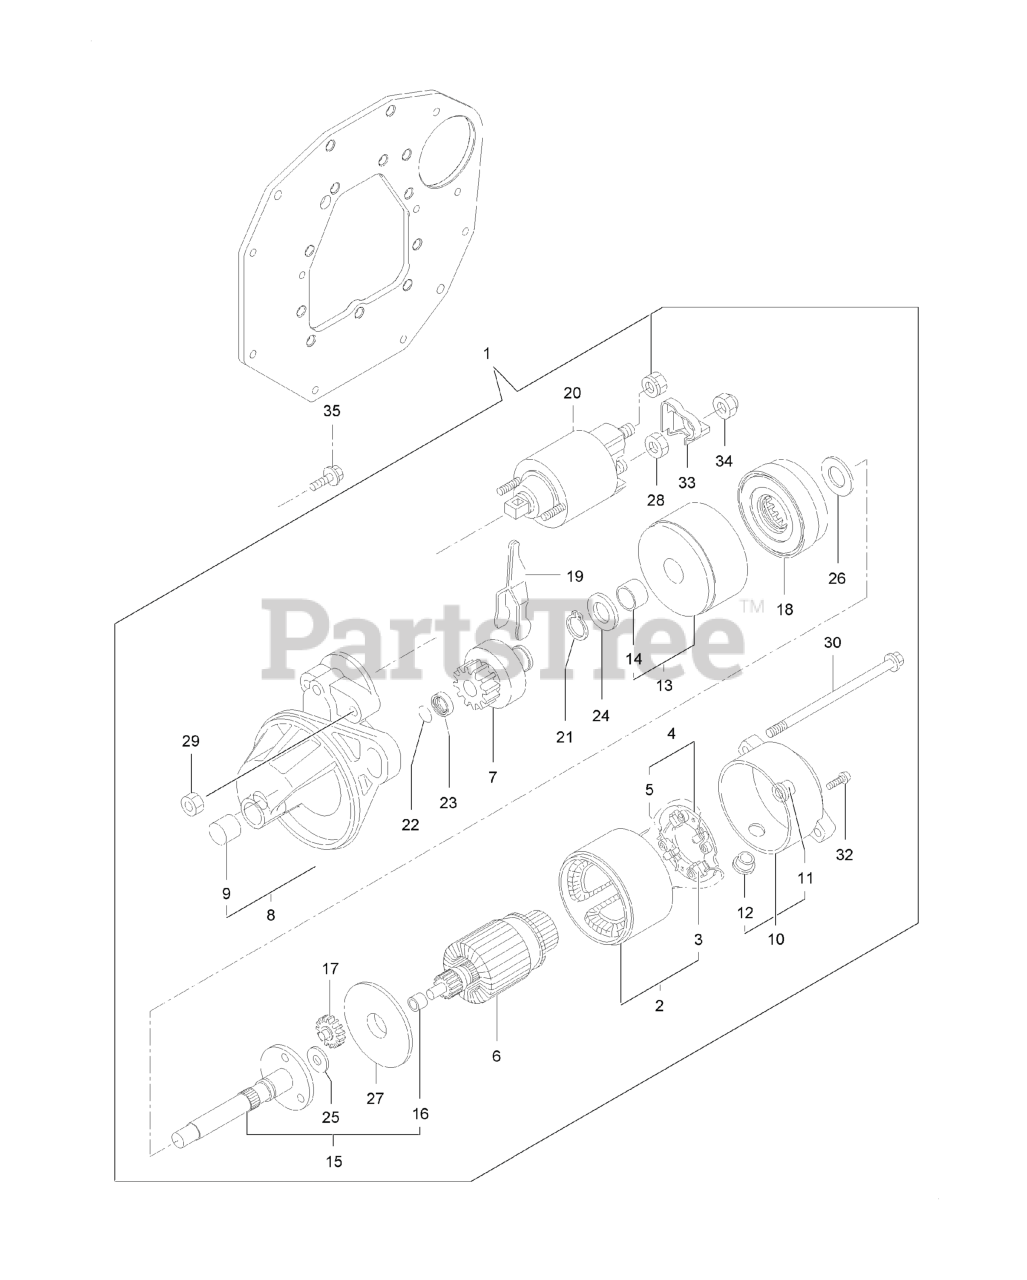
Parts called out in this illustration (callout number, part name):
1	STARTER ASM
2	YOKE ASM
3	STARTER KIT
4	HOLDER ASM
6	ARMATURE ASM
7	CLUTCH ASM
8	HOUSING ASM
9	BEARING, NEEDLE 1
10	FRAME ASM
11	BEARING
13	BEARING ASM
14	Bearing
15	SHAFT ASSY 1
16	Bearing
20	SWITCH ASM
30	BOLT-THROUGH
33	COVER-TERMINAL
